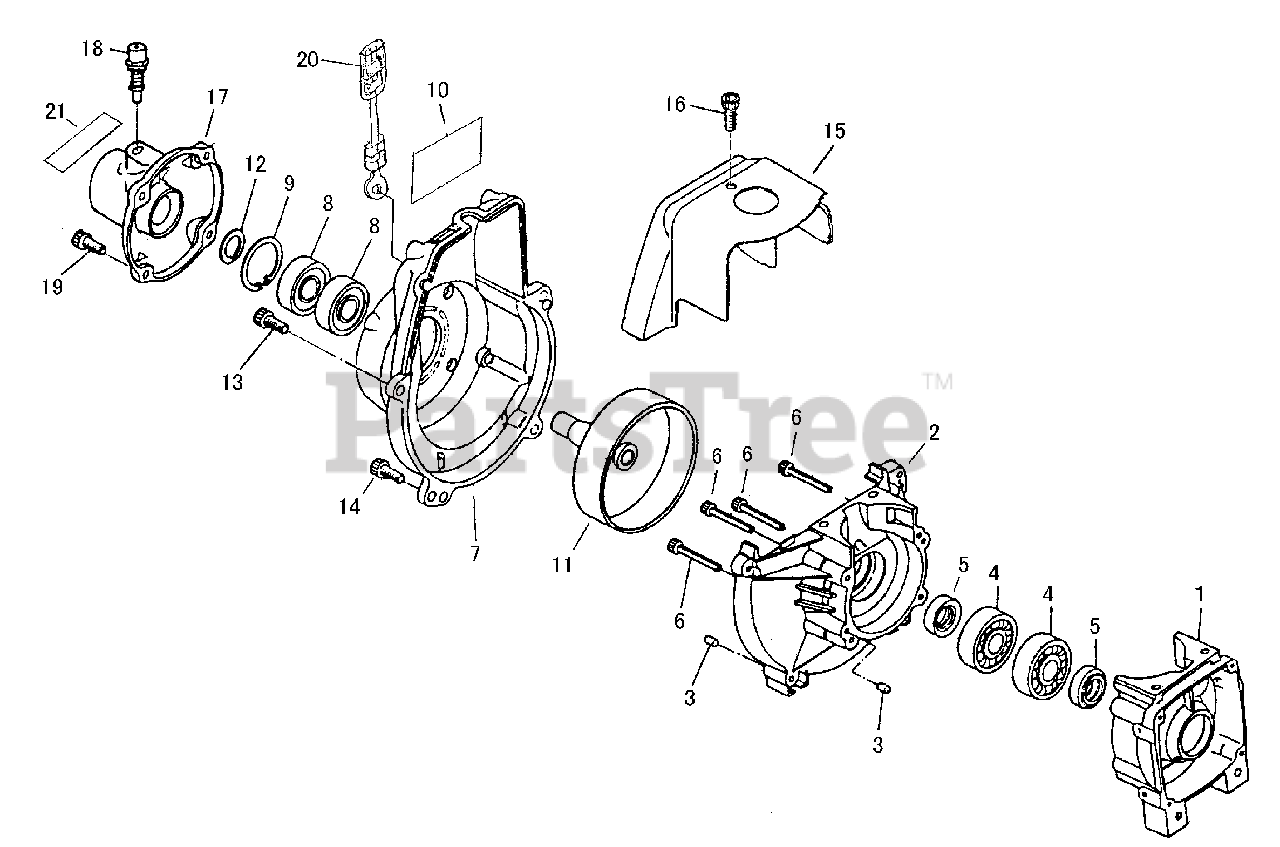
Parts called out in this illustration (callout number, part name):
1	CRANKCASE S
2	CRANKCASE M
3	PIN, LOCATING 5×10
4	BEARING, BALL 6202C3
5	SEAL, OIL 16
6	BOLT 5×30
7	COVER, FAN
8	BEARING, BALL 6002 DDU
9	RING, SNAP Ø32
10	LABEL, TRADE
11	DRUM, CLUTCH
12	RING, SNAP
13	BOLT M5×20
14	BOLT M5×35
15	COVER, ENGINE
16	BOLT 5×14
17	CUSHION, AV
18	PIN ASSY
19	BOLT M5×20
20	LEAD - GROUND
21	LABEL, TRADE
